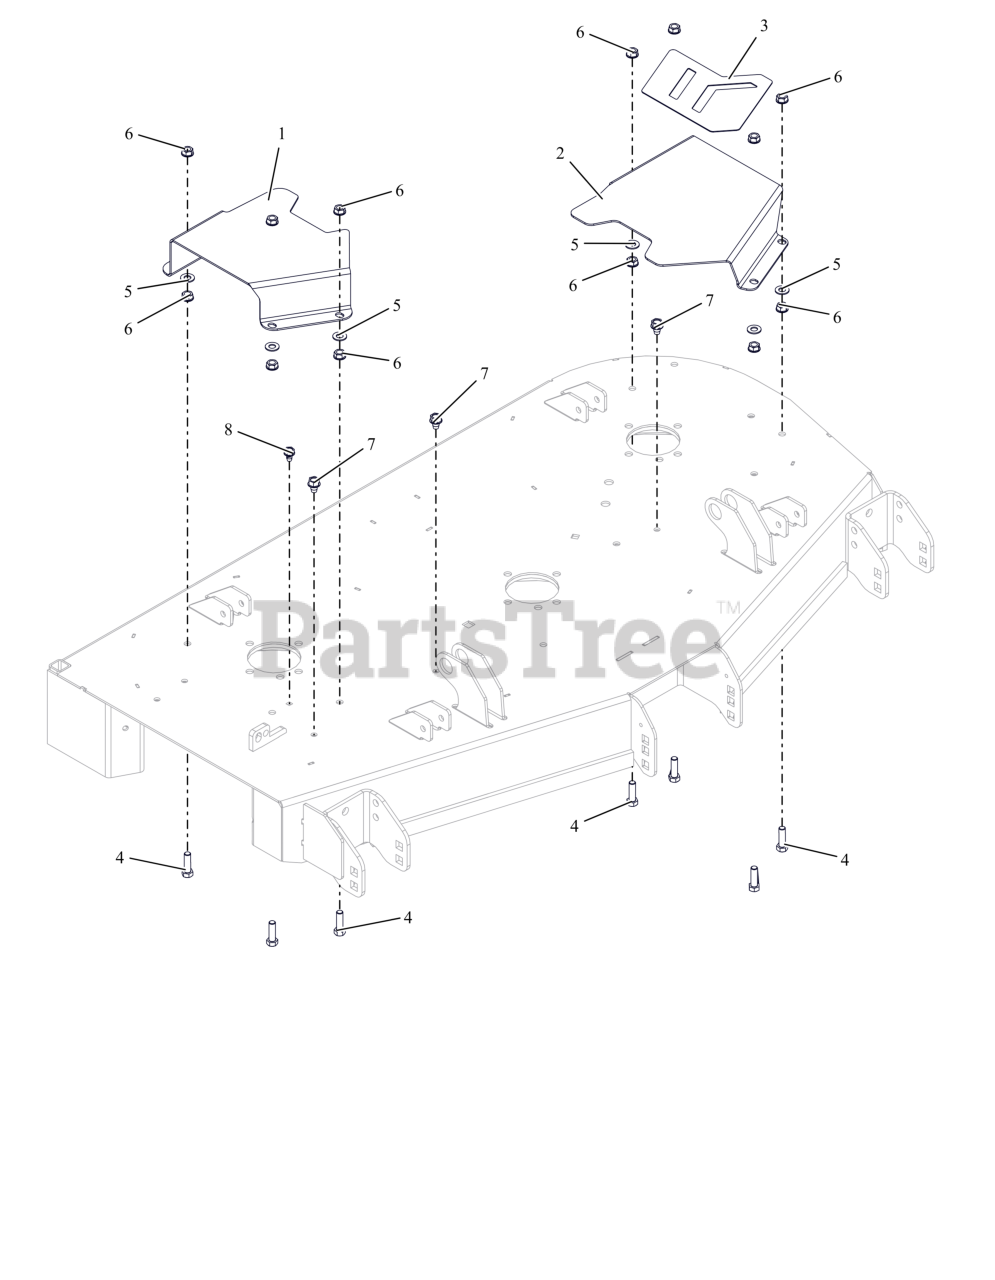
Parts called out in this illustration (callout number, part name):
1	COVER, BELT 48" RIGHT
2	COVER, BELT 48" LEFT
3	GRIP TAPE 48 BELT COVER
4	BLT, HEX .38-16X1.25 G5 ZCC
5	WSHR,FLT .406X.812X.065 ZCC
6	NUT, SPNLK-FLG .38-16 G5 ZCC
7	SCR,TAP .375-16X.50 HWH TR ZCC
8	SCR,TAP .312-18X.50 HWH TR ZCC
